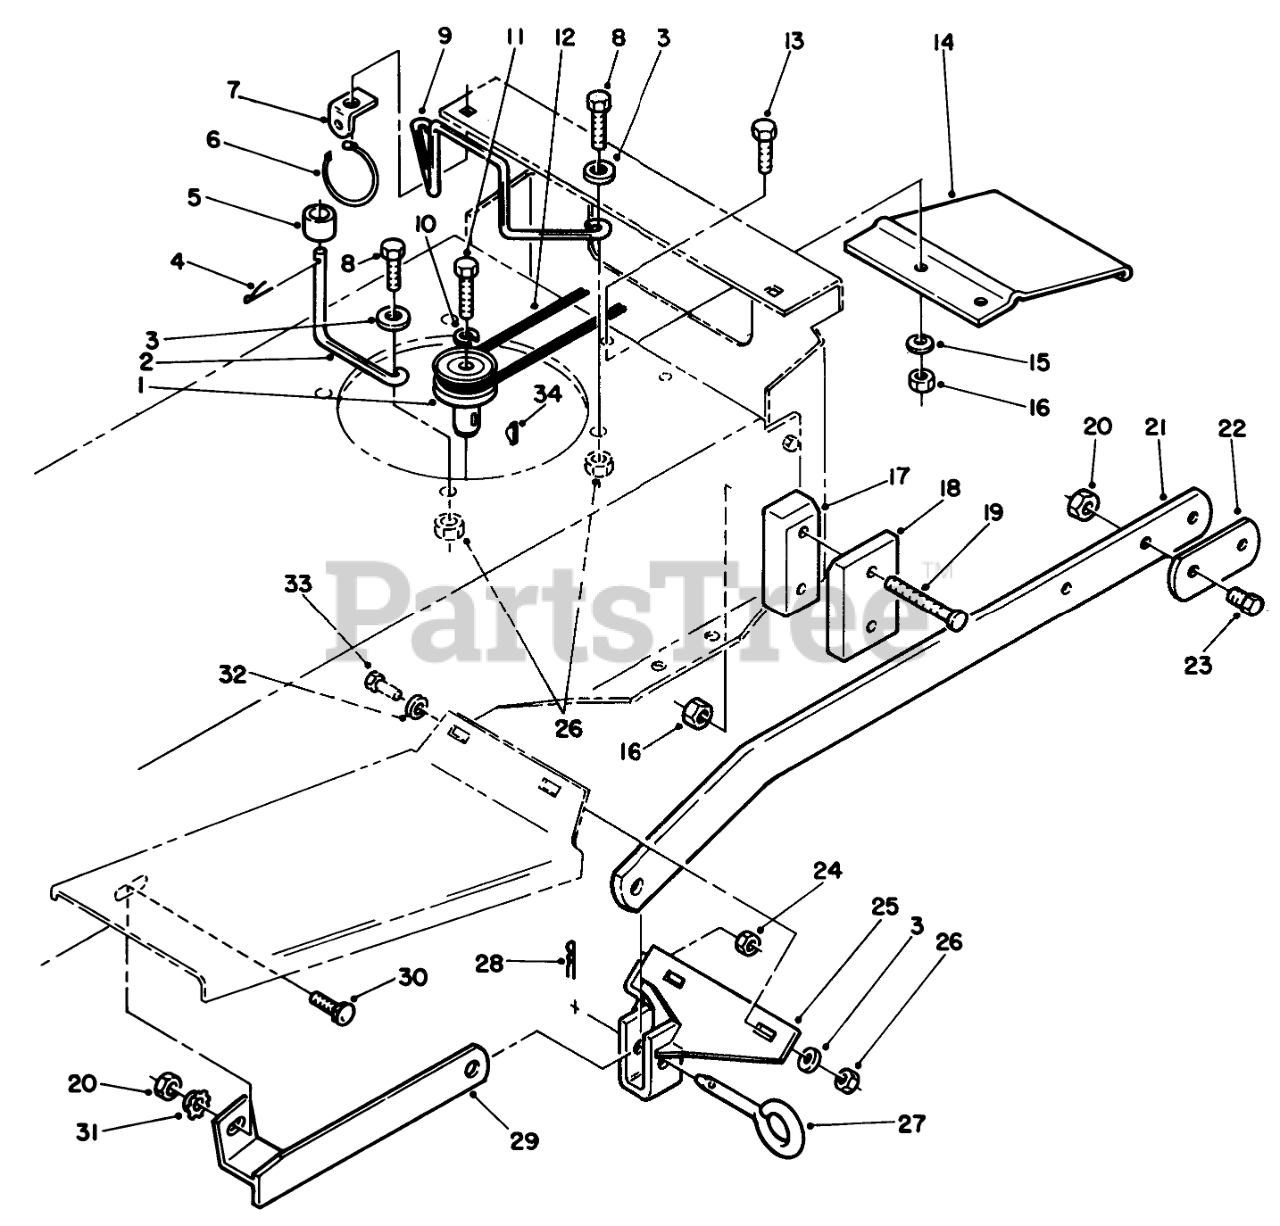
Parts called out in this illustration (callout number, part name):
1	PULLEY-DRIVER
2	GUIDE-BELT
3	WASHER-PLAIN
4	PIN-COTTER
5	SPACER
6	TIE-PLASTIC
7	CLIP - SPRING
8	SCREW-HH
9	BELT-GUIDE
10	WASHER-LOCK
11	Screw
12	V-BELT
13	SCREW-HH
14	SHOE-BELT R
15	WASHER-FLAT
16	NUT-LOCK, NI
17	SPACER-RUB BLOCK R
18	Block Rubber
19	Screw-Pan Hd.
20	NUT-LOCK, NI
21	Bar-Pivot
22	SPACER R
23	SCREW-HH
24	Nut
25	ASS'Y-BRACKET LH R
26	NUT-LOCK, NI
27	PIN-TOOL
28	Hairpin Cotter
29	WELDMENT-BRACE L. R
30	BOLT-CARR
31	WASHER
32	WASHER-SPECIAL
33	SCREW-HH
34	HARD HI PRO KEY
